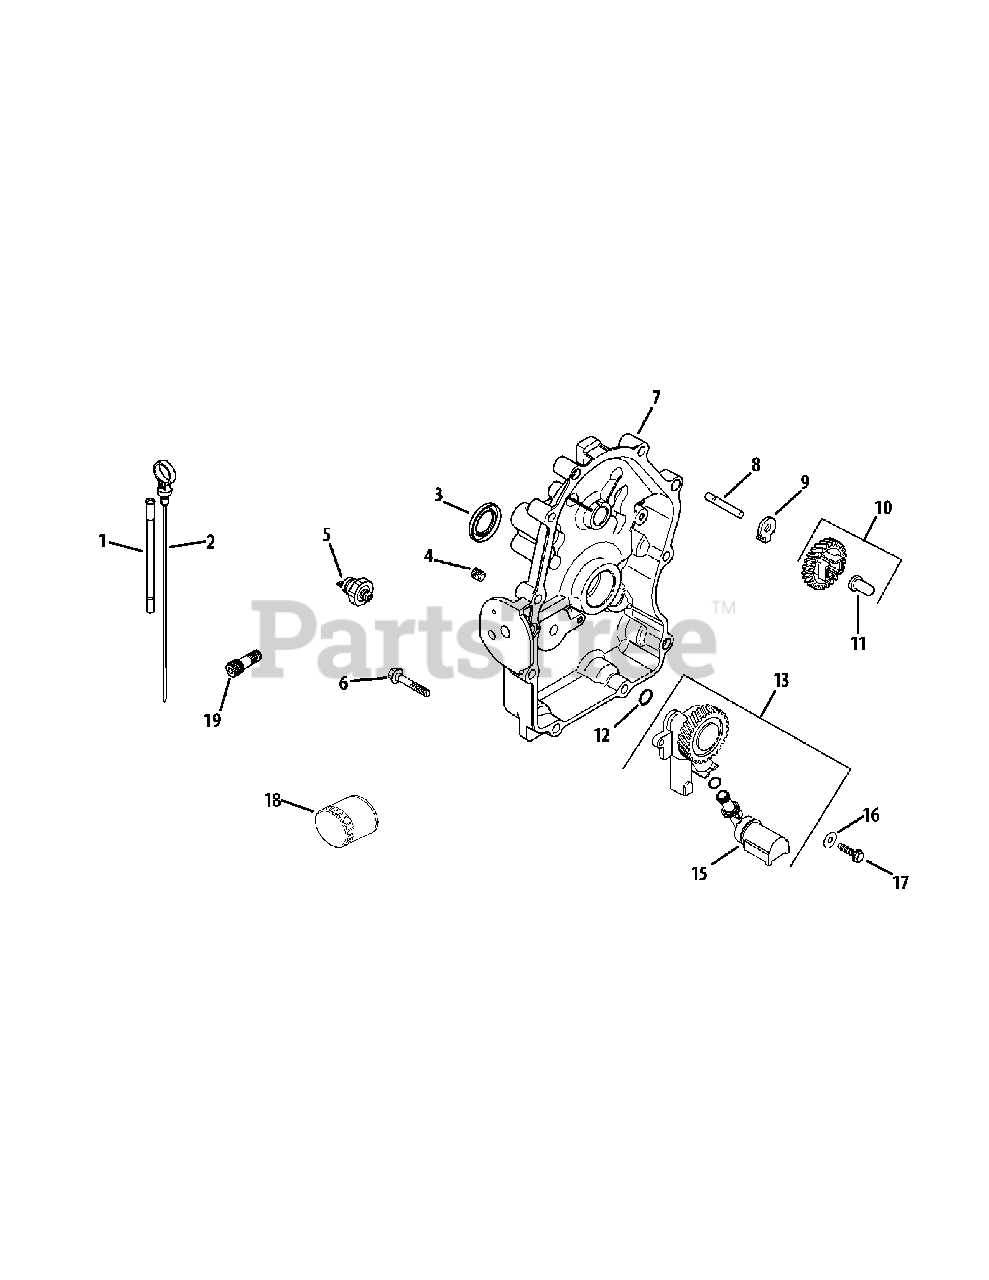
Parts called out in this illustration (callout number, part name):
1	Dipstick/Dipstick Tubes Kit
4	Countersink Pipe Plug, 1/8
5	Oil Pressure Switch
6	Flange Screw, M8 x 1.25 x 45
7	Closure Plate Assembly
8	Governor Gear Shaft
10	Governor Gear Kit w/ Pin
11	Governor Regulating Pin
13	Oil Pump Assembly Kit
13	Oil Pick-Up O-Ring
16	Flat Washer, 1/4 x 5/8
17	Thread Forming Screw
19	Oil Filter Nipple
